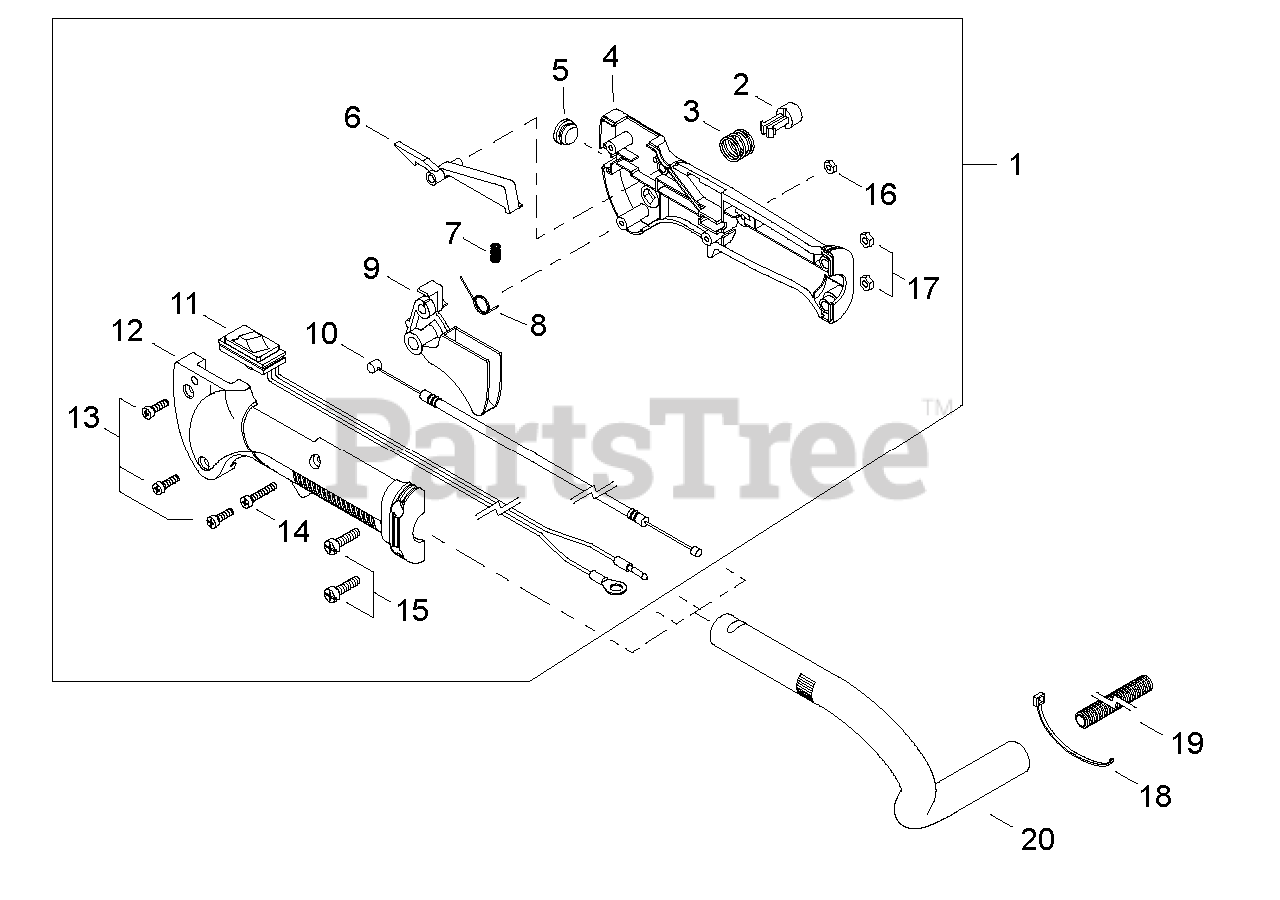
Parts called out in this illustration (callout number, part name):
1	THROTTLE CONTROL ASSY
2	BUTTON, THROTTLE LOCK
3	SPRING, COMPRESSION
4	CONTROL HANDLE - RIGHT
5	PLUG, RUBBER
6	LOCKOUT, THROTTLE
7	SPRING, COMPRESSION
8	SPRING, TORSION
9	TRIGGER, THROTTLE
10	CABLE, THROTTLE
11	SWITCH ASSY, ON-OFF
12	CONTROL HANDLE - LEFT
13	SCREW, TAPPING 4×16
14	SCREW M4×23
15	SCREW M5×20
18	STRAP, TIE
19	TUBE, FLEXIBLE
20	HANDLE, REAR
